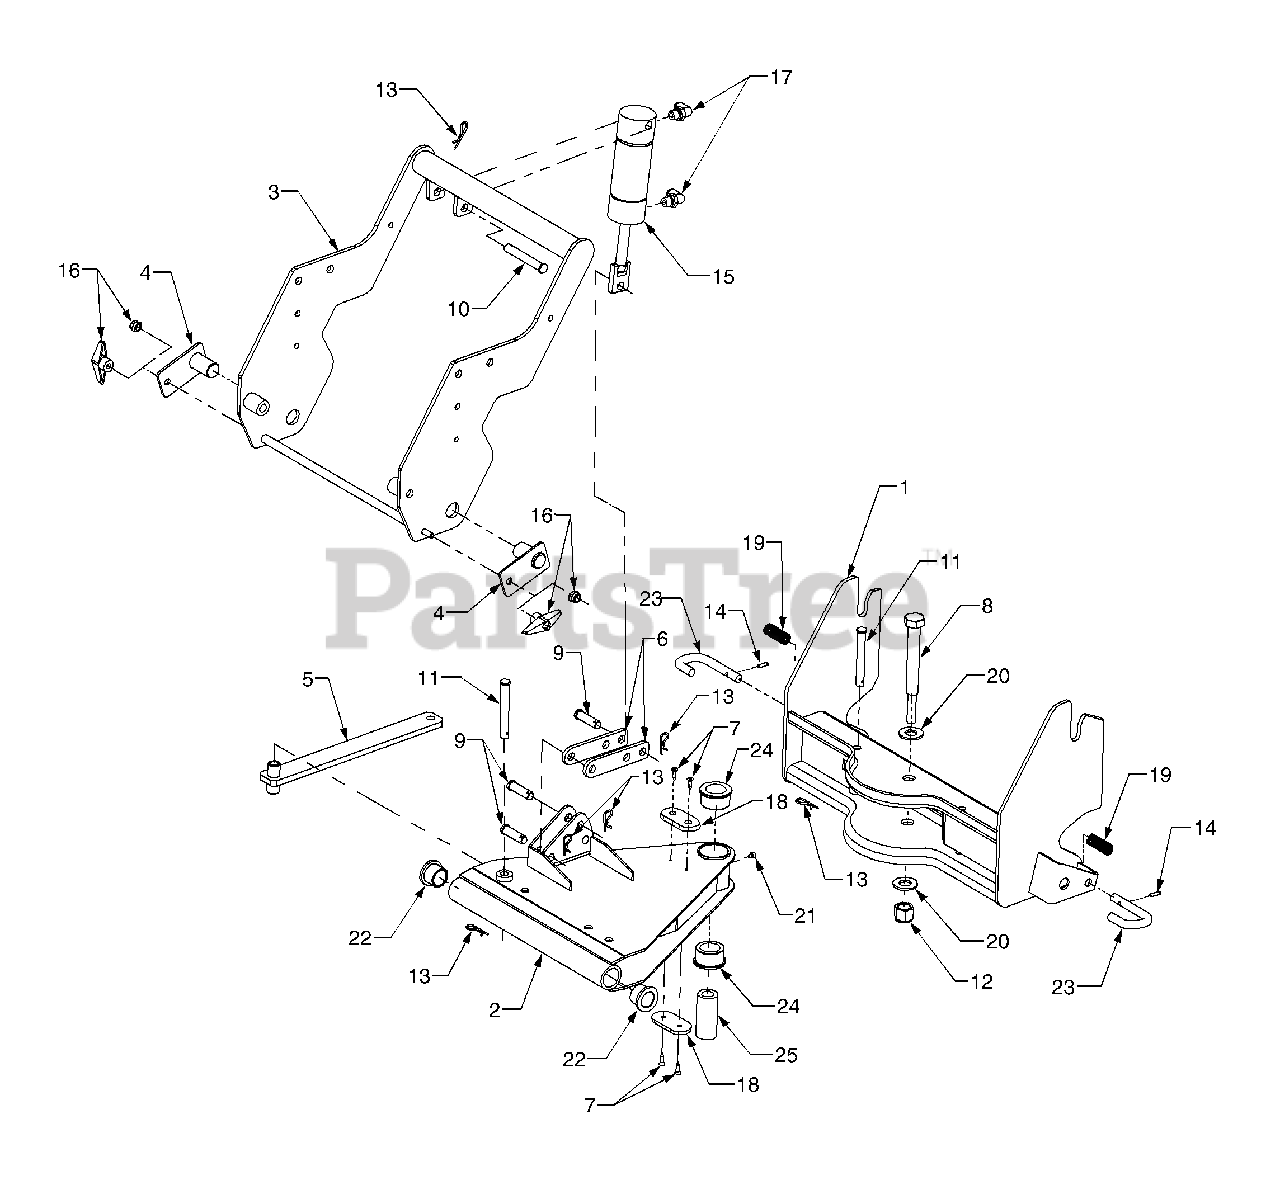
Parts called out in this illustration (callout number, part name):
1	Yoke Assembly, Hitch
2	Plate Assembly, Pivot
3	Plate Assembly, Mounting
7	Screw, Countersink, #10-12 x .75
8	Screw, Hex Cap 3/4-10 x 4.75 GR5
9	Pin, Clevis, .5 Dia x 1.59
10	Pin, Clevis, .494 Dia x 2.91
11	Pin, Clevis, .5 Dia x 3.375
12	Nut, Hex, 3/4-10
13	Pin, Internal Cotter
14	Pin, Spirol
15	Cylinder, Hitch Lift
16	Knob, Wing Nut, 5/16-18
17	Elbow, 90 Degree
18	Plate, Stab
19	Spring, Compression
20	Washer, Flat, .75 x 1.5 x .120
21	Fitting, Lube, 3/16 Drive
22	Bearing, Flange, 1.003 ID
23	Pin, Mower Support
24	Bearing, Flange, 1.252 ID
25	Pivot Shaft
